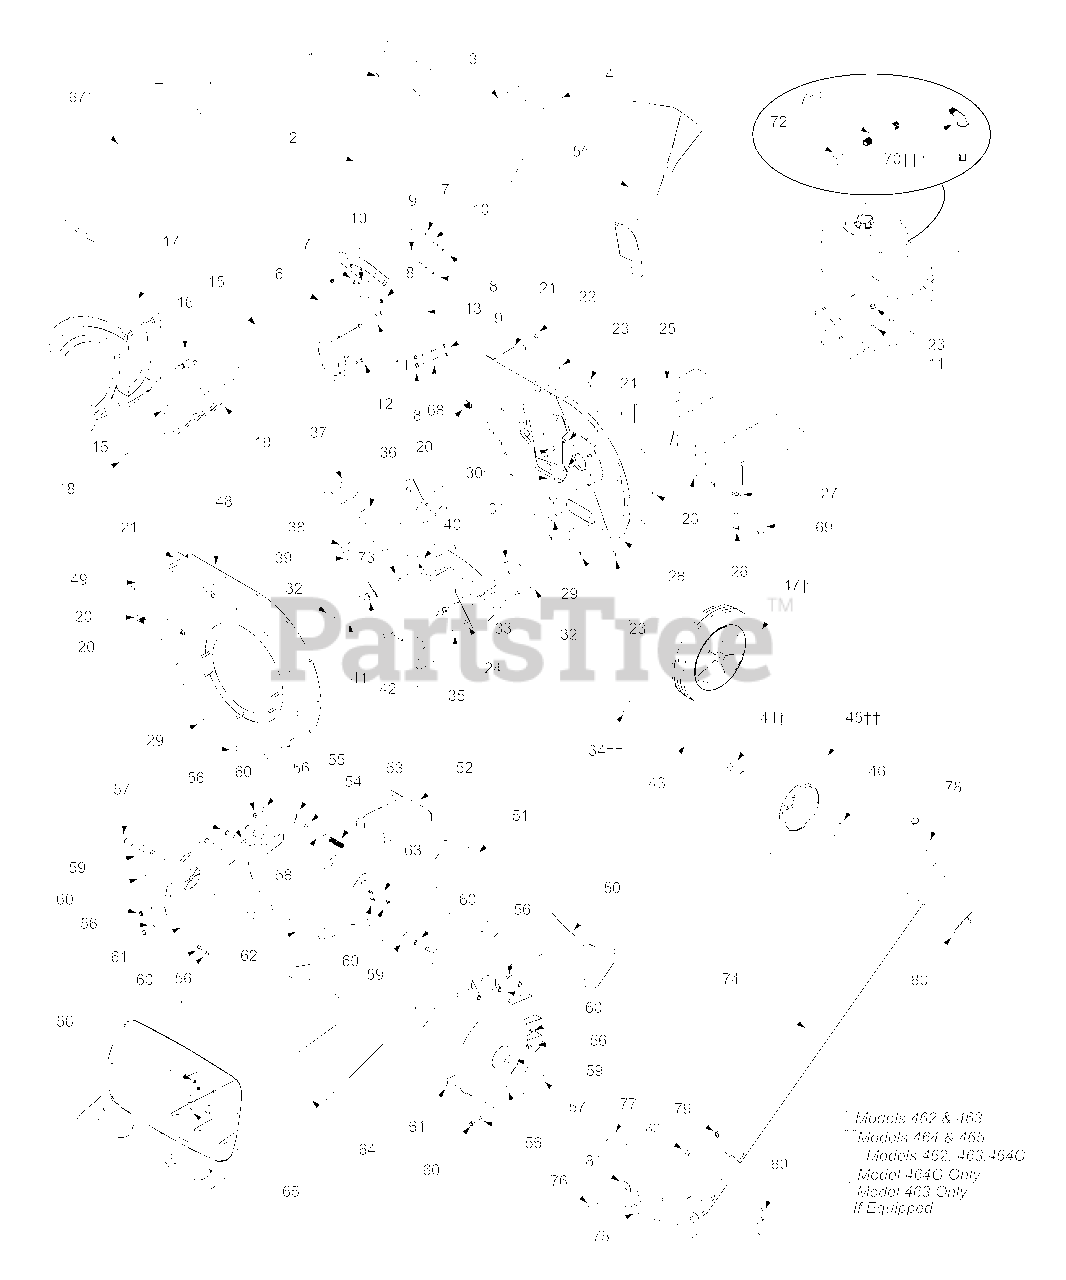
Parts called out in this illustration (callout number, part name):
1	Pop Rivet
2	Chipper Shredder Chute
3	Chute Flap
4	Chute Flap Strip
8	Hex Lock Nut 1/4-20
9	Hex Cap Screw 1/4-20 x 1.25
10	Flat Washer.28 ID x.74 OD
11	Bell Washer.340 ID x.872 OD
12	Hex Nut 5/16-18
15	Cotter Pin
16	Wing Knob 5/16-18
18	Clevis Pin
20	U-Nut 5/16-18
21	Spacer
22	Hex Lock Nut 1/4-20
23	Hex Lock Nut 5/16-18
24	Lock Washer 5/16
26	Hex Cap Screw 5/16-18 x 1.50
27	Bell Washer 5/16 x 1.0
29	Hex Cap Screw 5/16-18 x.625
30	Hex Cap Screw 5/16-24 x.75
31	Chipper Blade
32	Hex Cap Screw 5/16-24 x 1.0
33	Impeller Assembly
34	Flat Washer
35	Hex Lock Nut 5/16-24
36	Retainer Pin Clip
37	Flail Blade
38	Clevis Pin
40	Flat Washer 3/8 x 1.25
41	Shredder Blade
42	Hex Cap Screw 3/8-24 x 2.25
43	Axle Assembly
44	Spacer
45	Wheel Complete 10.0 x 4.0 Gray
46	Push Cap
47	Wheel Complete 10.0 x 2.5 Plastic
49	Hex Cap Screw 1/4-20 x 3.75
53	Compression Spring 1.75
54	Flat Washer
55	Cotter Pin
56	Flat Washer.330 ID x.630 OD
57	Hex Cap Screw 5/16-18 x 1.0
58	Spacer,.375 ID x 2.50 LG
59	Flat Washer.320 ID x 1.25 OD
60	Hex Lock Nut 5/16-18
61	Hopper Collar
63	Lock Rod
64	Hopper Assembly
65	Hex Cap Screw 5/16-18 x.75
67	Tamper Plug
68	Washer,.320 ID x.93 OD
69	Screw, 3/8-16 x 1.250
70	Elbow Fitting
71	Oil Drain Pipe
72	Oil Drain End Cap
73	Lock Washer, 3/8
76	Hex Cap Screw, 3/8-16 x.88
77	Clevis Pin,.625 x 2.4
78	Clevis Pin,.50 x 4.62
79	Hex Nut, 3/8
80	Spring Pin
81	Flat Washer,.411 x 1.25 x 1.0
82	Lock Washer, 3/8
